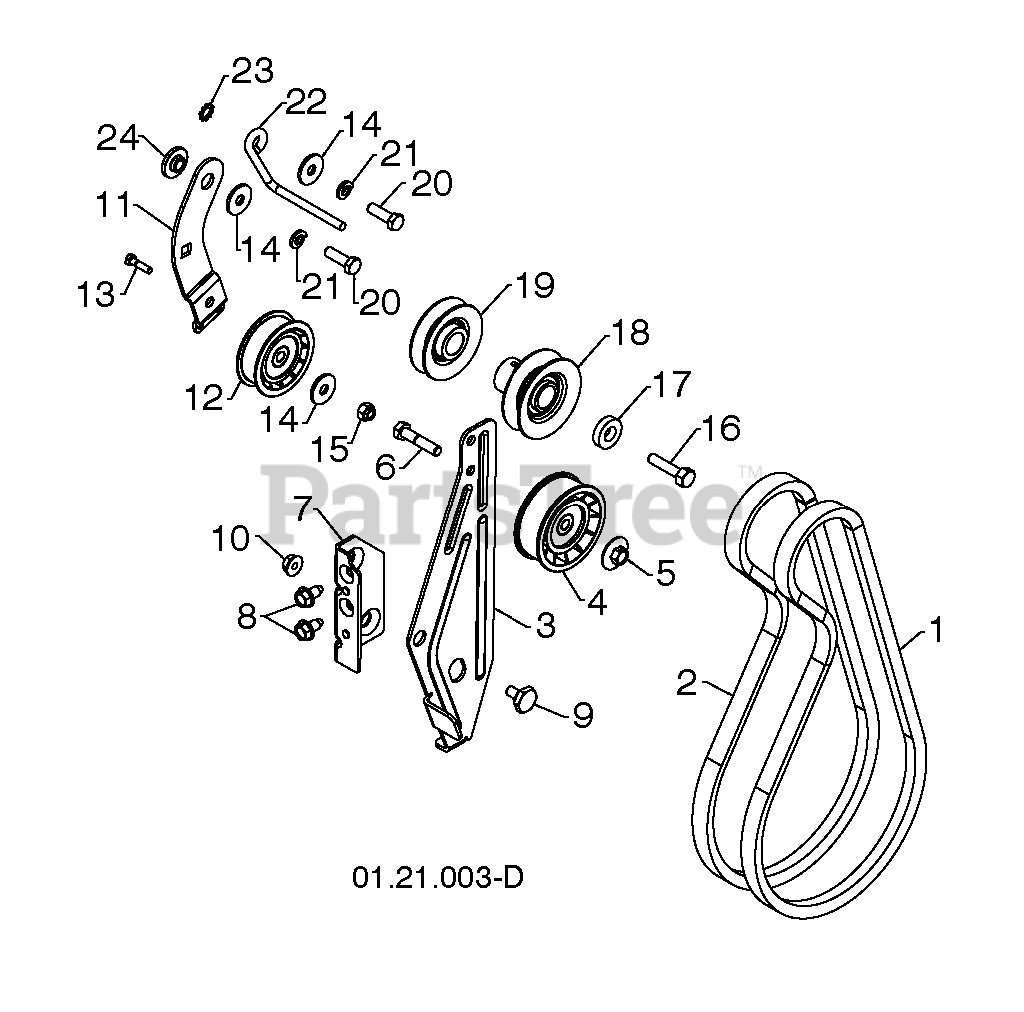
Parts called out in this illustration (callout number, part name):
1	VBELT; IMPELLER_39.09
2	V-BELT TRACTION 34.25
3	ARM.IDLER.BRAKE.
4	PULLEY.IDLER.W/SPACER.
5	RP BRACKET.IDLER.PIVOT
6	NUT.FLANGE.HEX.5/16X18.BLACK
7	HEX BOLT
8	BOLT.SHOULDER.1/2X12
9	BOLT.5/16HEX.WHS.HD
10	NUT.LOCK.5/16-18
11	ARM, IDLER
12	PULLEY.W/SPACER.2.25
13	STEEL WASHER
14	NUT.71038.31-18.HEX.NYLOCK
15	BOLT.5/16-18X1-1/4 FULL.THREAD
16	SCREW, HEX HD 3/8-24 X 1-3/8
17	WASHER, FLAT 3/8
18	PULLEY.ENG.IMPELLER.SNOW
19	PULLEY.ENG.TRACTION
21	WASHER.LOCK.HVY.HLCL.SPR.5/16
22	BELT.GUIDE.RH
23	WASHER EXT TOOTH LOCK 5/16
24	RP BUSHING, IDLER PIVOT
